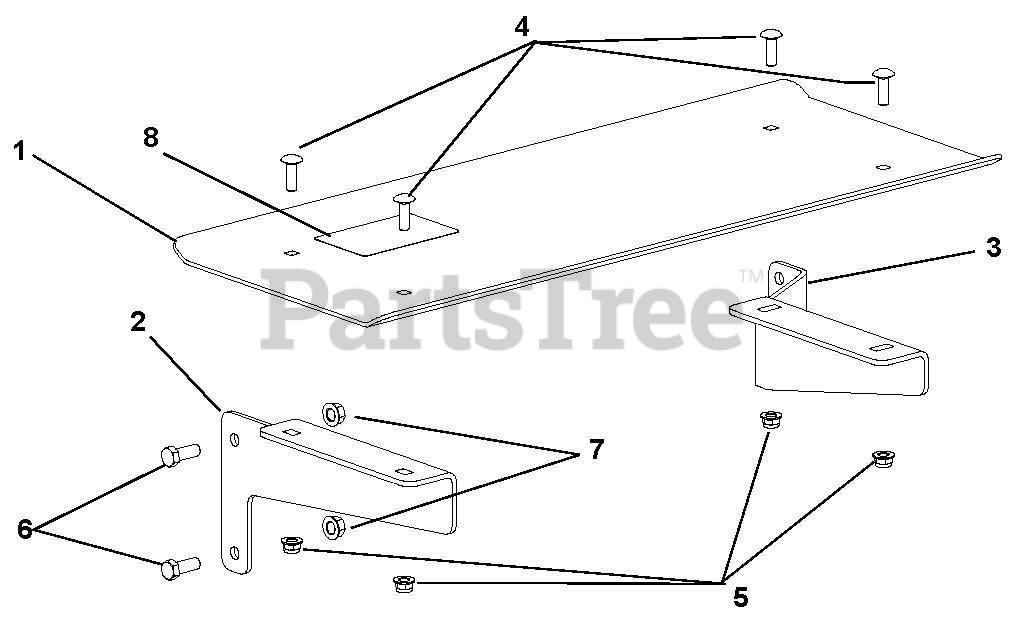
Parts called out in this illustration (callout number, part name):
1	TABLE, WORK - LOG SPLITTER
2	BRKT, FRONT - WORK TABLE
3	BRKT, REAR - WORK TABLE
4	@BLT-RHDSSQNK .31-18X1.00 G5YZ
5	@NUT-LK-NYL-FLG .31-18 YWZC
6	@BLT-HEX .38-16X1.00 GR5 YWZC
7	@NUT-LK-TOP-FLG .38-16 YWZC
8	DECAL,SPLITTER TABLE
